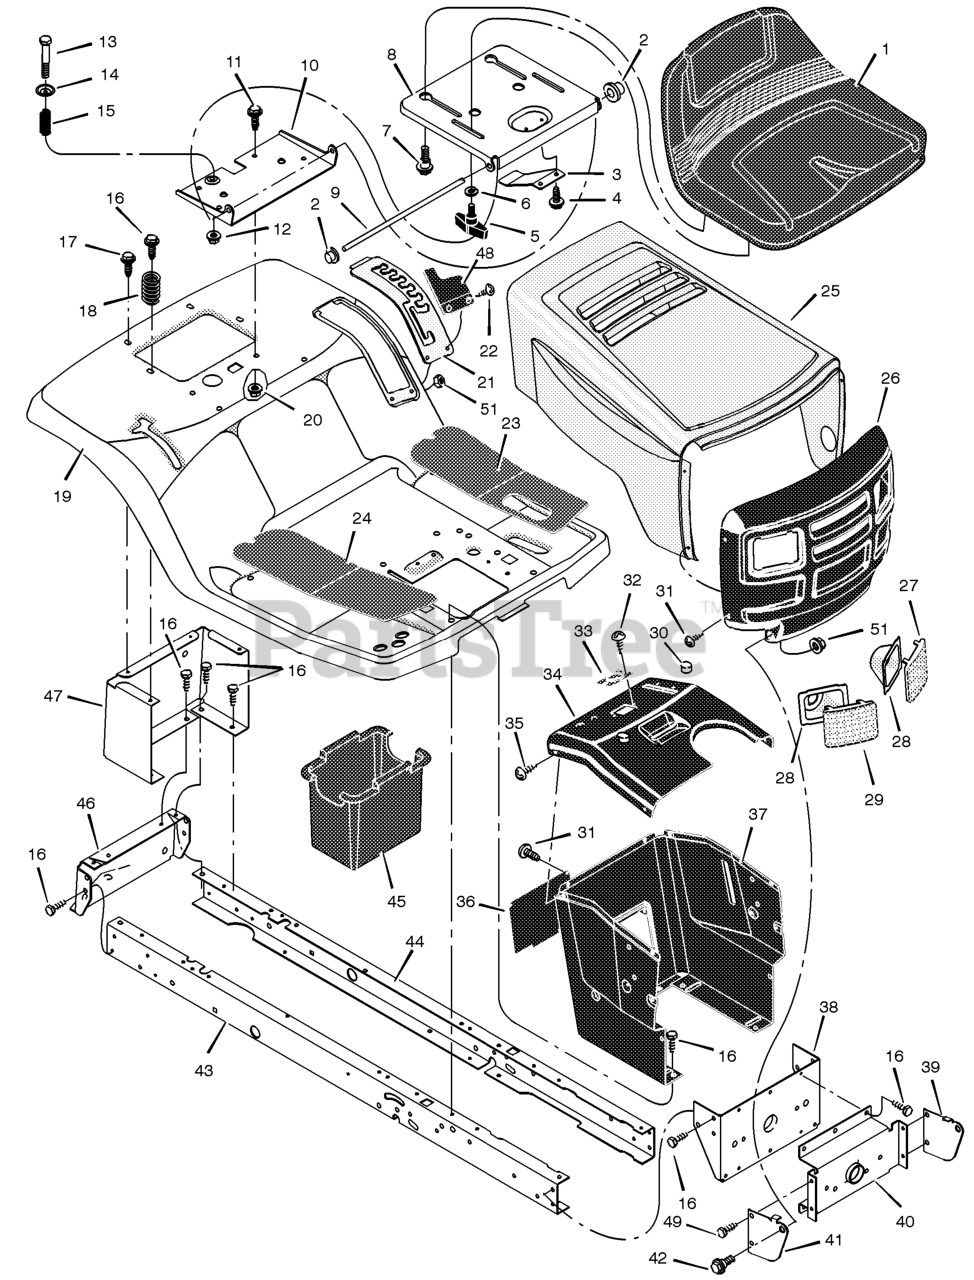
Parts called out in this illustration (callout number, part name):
1	Seat
2	Cap, Push 0n
5	Bolt, Wing
6	Washer
7	Bolt, Shoulder
8	Support, Seat
9	Rod, Pivot
10	Bracket, Pivot
11	Bolt
13	Bolt, Shoulder
15	Spring
19	Deck, Seat
20	Nut
21	Plate, Index
23	Mat, Left
24	Mat, Right
27	Lens, Left
29	Lens, Right
30	Bumper
31	Screw
33	Bearing, Steering
36	Panel, Access
37	Support, Dash
38	Bracket, Rear Hanger
39	Support, Left Grille
40	Axle, Hanger
41	Support, Right Grille
42	Bolt, Shoulder
43	Frame, Right
44	Frame, Left
45	Container, Battery
46	Plate, Hitch
47	Panel, Rear
48	Cover, Detent
50	Locknut
51	Locknut
